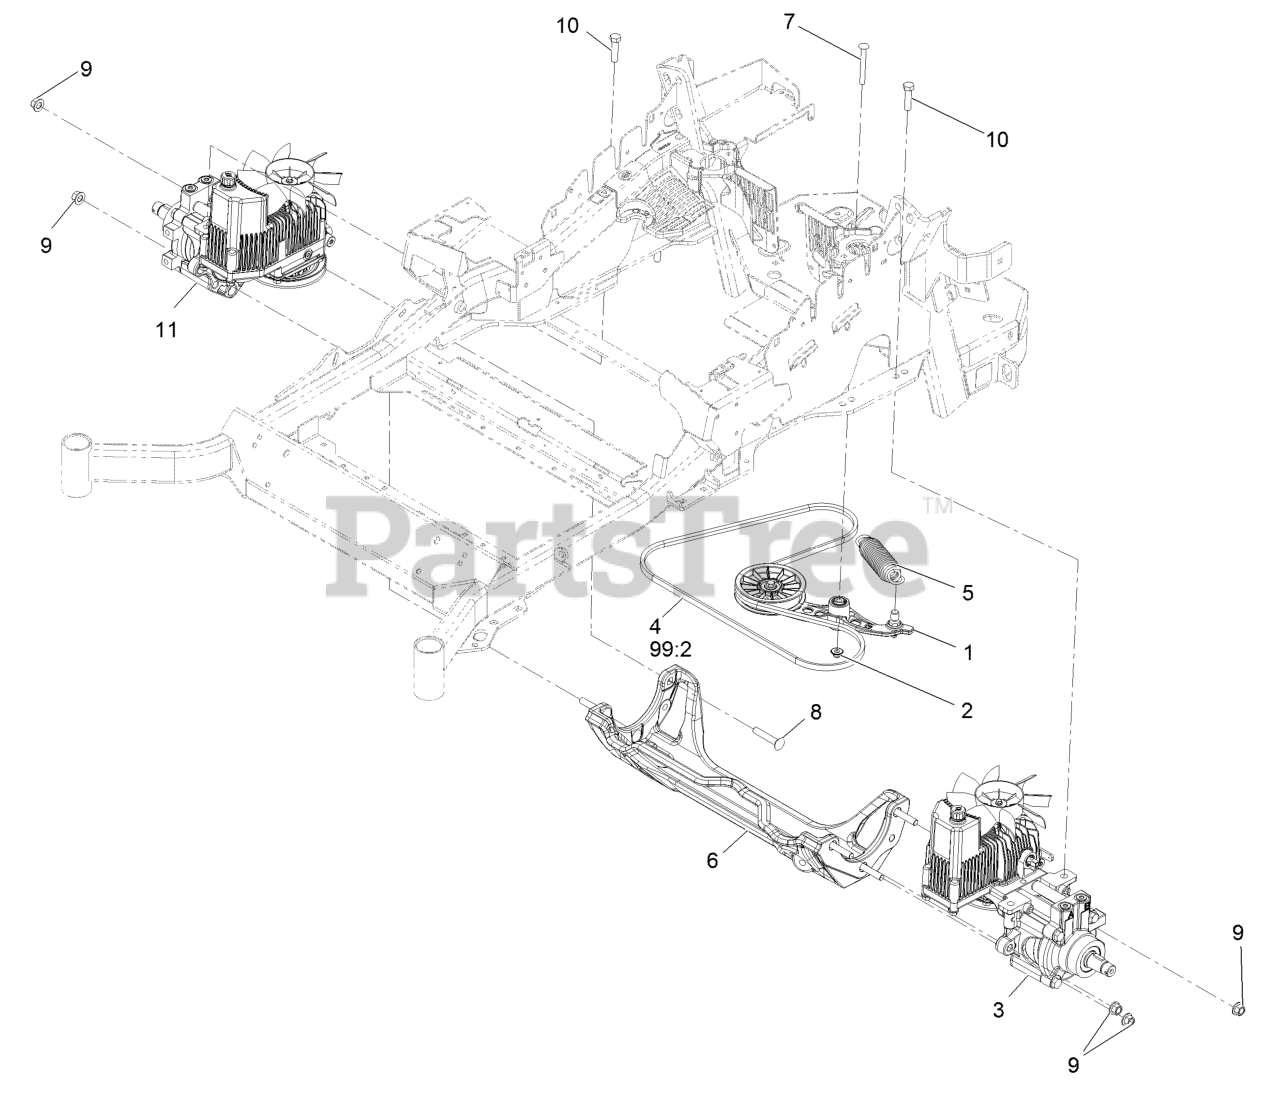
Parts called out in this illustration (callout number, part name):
1	PUMP IDLER ASM
2	Nut-Nyloc 3/8-16 Flg
3	LH Hydro ASM (16Cc W/ Shock)
4	BELT
5	SPRING-EXTENSION
6	CRADLE-HYDRO
7	BOLT-SHOULDER, CARRIAGE 3/8-16 X 3 1/2
8	SCREW-CARR
9	Nut-Lock 1/2-13
10	SCREW-HH
11	RH Hydro ASM (16Cc W/ Shock)
99:2	BELT
